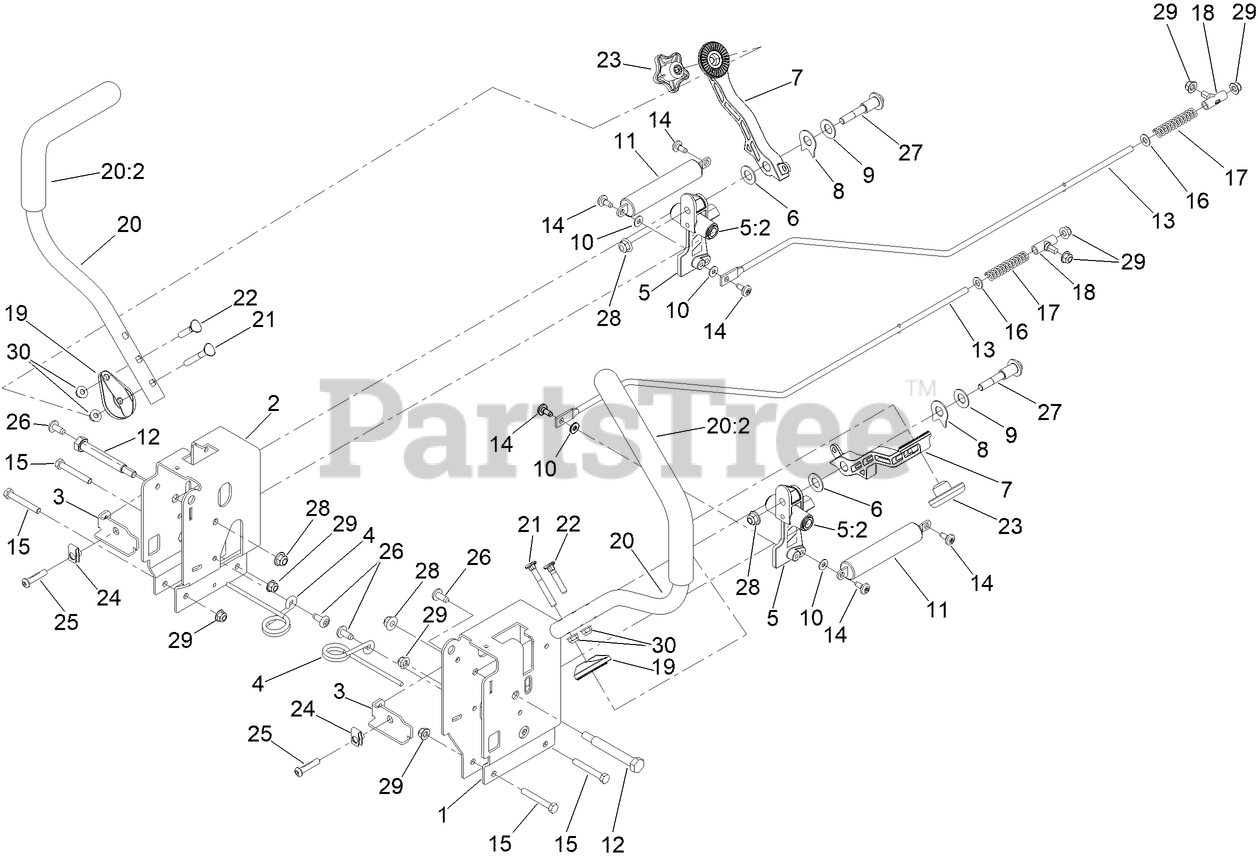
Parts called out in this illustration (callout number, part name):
1	CONTROL BOX - LH G7
2	CONTROL BOX - RH G7
3	ADJUSTMENT PLATE-CONTROL BOX
4	SPRING-TORSION
5	PIVOT ARM ASM
5:2	BUSHING-FLANGE
6	WASHER-NYLON
7	ARM-CONTROL, 32 TEETH
8	SPACER, ANTI-ROTATION
9	WASHER-BELLEVILLE
10	WASHER
11	DAMPER-NON CAVITATING
12	BOLT-PIVOT
13	ROD - HYDRO
14	SCREW-SHOULDER
15	SCREW-HH
16	WASHER-PLAIN
17	SPRING-COMPRESSION
18	MOUNT-ROD, HYDRO
19	DISC-ADJUSTMENT HANDLE, 32 TEETH
20	HANDLE-CONTROL,
21	SCREW-HANDLE
22	SCREW-HANDLE
23	KNOB-HANDLE
25	SCREW-HSBH
27	BOLT-PIVOT
28	NUT-HF, NI
29	NUT-HF, NI
30	NUT-HF
